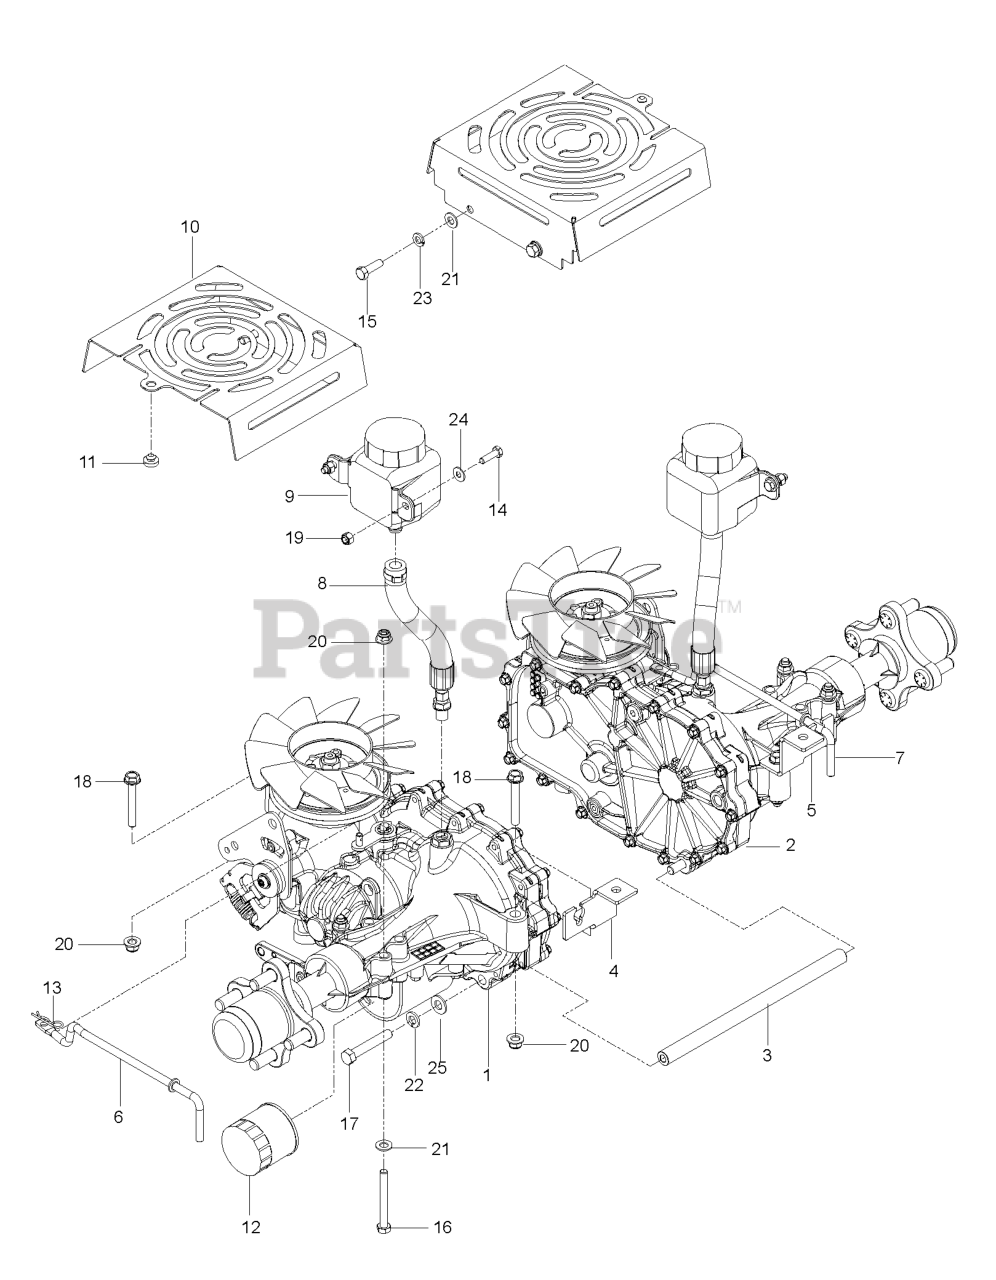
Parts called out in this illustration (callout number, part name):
1	HG_TRANS, ZT-3400, LT
2	HG_TRANS, ZT-3400, RT
3	TUBE, SPACER, 3400
4	BRACKET.TRANS.LT.BLACK
5	BRACKET, TRANS, RT BLACK
6	LINKAGE, LEFT BYPASS
7	LINKAGE, RIGHT BYPASS
8	HOSE ASSY, EXPANSION
9	TANK.EXPANSION.350ML 71328
10	SHIELD, FAN, BLK
11	GROMMET, BUMPER
12	HG_FILTER, ZT4800 52114
13	HAIRPIN #2
14	HCS 1/4-20X7/8 GR5
15	HCS 5/16C X 1
16	HCS 5/16C X 2-3/4
17	HCS 3/8-16X2-1/4 LOC PATCH GR8
18	HHFS 5/16-18 X 2.25 GD 5
19	NUT.1/4-20.HEX.NYLOC.ZD
20	5/16-18 NYLOC FLANGE NUT
21	FLAT WASHER 5/16 SAE
22	SLW 3/8 STD
23	WASHER.LOCK.HVY.HLCL.SPR.5/16
24	WASHER 1/4 SAE
25	WASHER 3/8 SAE FLAT
